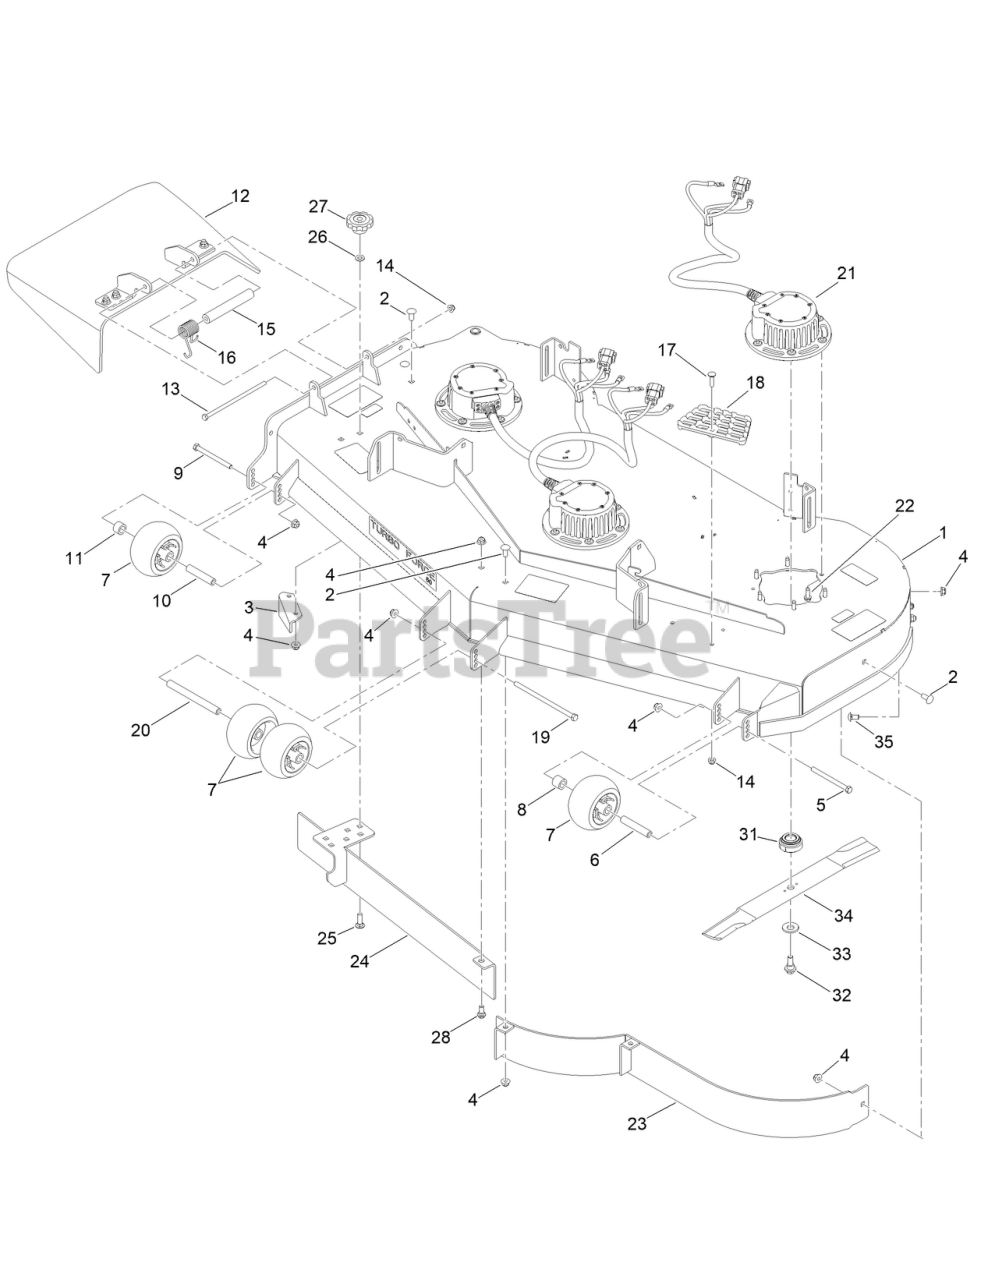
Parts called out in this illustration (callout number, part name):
1	DECK ASM-60IN
2	SCREW-CARR
3	BAFFLE-DISCHARGE
4	NUT-HF, NI
5	SCREW-HH
6	TUBE-SPANNER
7	ROLLER-SCALP, ANTI
8	TUBE-SPACER
9	SCREW-HH
10	TUBE-SHAFTING
11	TUBE-SPACER
12	RUBBER DEFLECTOR ASM
13	SCREW-HH
14	NUT-HF, NI
15	SPACER
16	SPRING-TORSION
17	SCREW-CARR
18	STEP-DECK
19	SCREW-HH
20	SPACER-WHEEL
21	MOTOR/GEN-48V,
22	SCREW-THD ROLL, HWH
24	BAFFLE-TURBO FORCE
25	BOLT-CARR
26	WASHER-HARDENED
28	BOLT-SHOULDER
31	RETAINER-BLADE
32	SCREW-SHOULDER,HWH
33	WASHER-BELLEVILLE
34	BLADE-20.5IN, MED SAIL
35	SCREW-CARR
